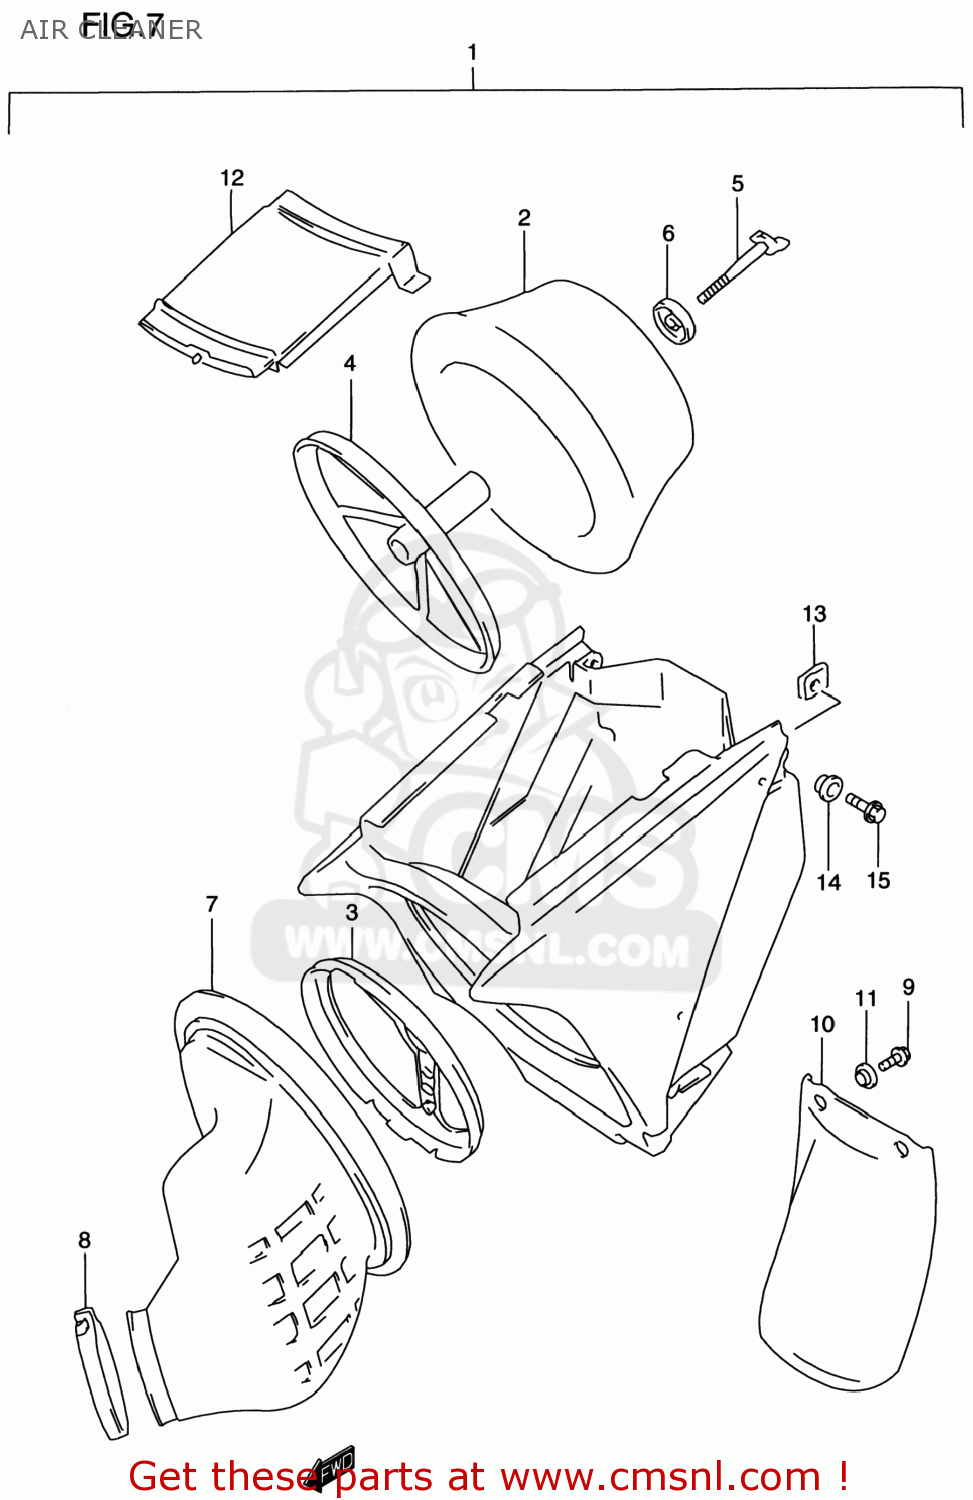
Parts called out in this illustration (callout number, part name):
1	CLEANER ASSY,AIR
2	FILTER ASSY
3	BASE,FILTER
4	HOLDER,FILTER
5	BOLT,WING
6	WASHER,AIR CLEANER
7	TUBE,OUTLET
8	CLAMP
9	BOLT
10	MUDGUARD
11	COLLAR
12	CAP,AIR CLEANER
13	HOLDER,REAR BU
14	WASHER
15	SCREW
